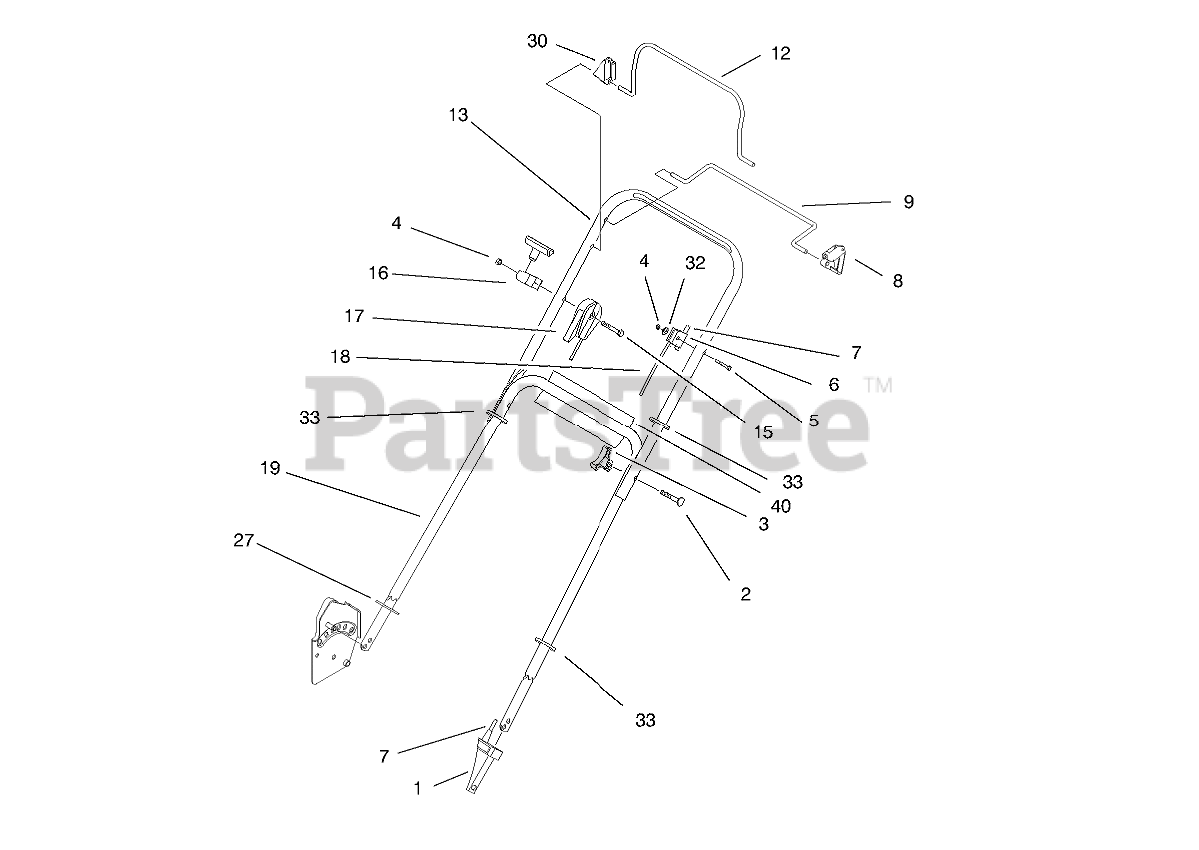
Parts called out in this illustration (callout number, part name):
1	ANCHOR-CABLE
2	SCREW
3	Knob
4	NUT-LOCK, NI
5	SCREW-HANDLE
6	ANCHOR - CABLE
7	CABLE - TRACTION
8	STOP-PIVOT
9	Bail-Control
12	Bail-Flywheel Brake
13	Handle-Upper
15	SCREW-HH
16	GUIDE-ROPE
17	CABLE - THROTTLE
18	BRAKE CABLE ASM
19	Hand e Lower
27	GUARD - HANDLE
32	WASHER-FLAT
33	TIE-CABLE
40	DECAL - OPERATION
